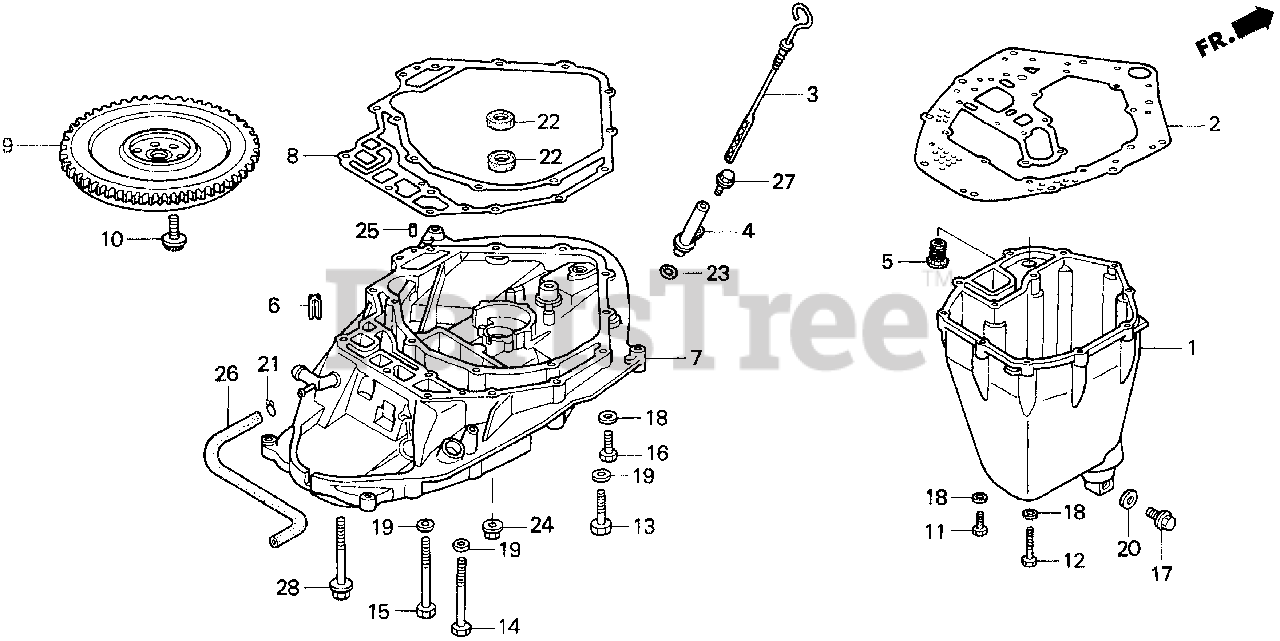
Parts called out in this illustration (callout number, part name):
1	PAN, OIL *TGRAY* (GRAY)
2	GASKET, OIL PAN
3	DIPSTICK, OIL
5	GROMMET, WATER TUBE
8	GASKET, MOUNT CASE
9	FLYWHEEL *TBLACK* (BLACK)
10	BOLT (12MM)
11	BOLT, HEX. (8X35)
12	BOLT, HEX. (8X55)
13	BOLT, HEX. (10X47)
14	BOLT, HEX. (10X110)
15	BOLT, HEX. (10X90)
16	BOLT, HEX. (8X25)
17	BOLT, DRAIN PLUG
18	WASHER, PLAIN (8MM)
19	WASHER, PLAIN (10MM)
20	WASHER, DRAIN PLUG (12MM)
24	NUT, FLANGE (10MM)
25	PIN, DOWEL (6X10)
27	BOLT, FLANGE (6X12)
28	BOLT, FLANGE (10X110)
